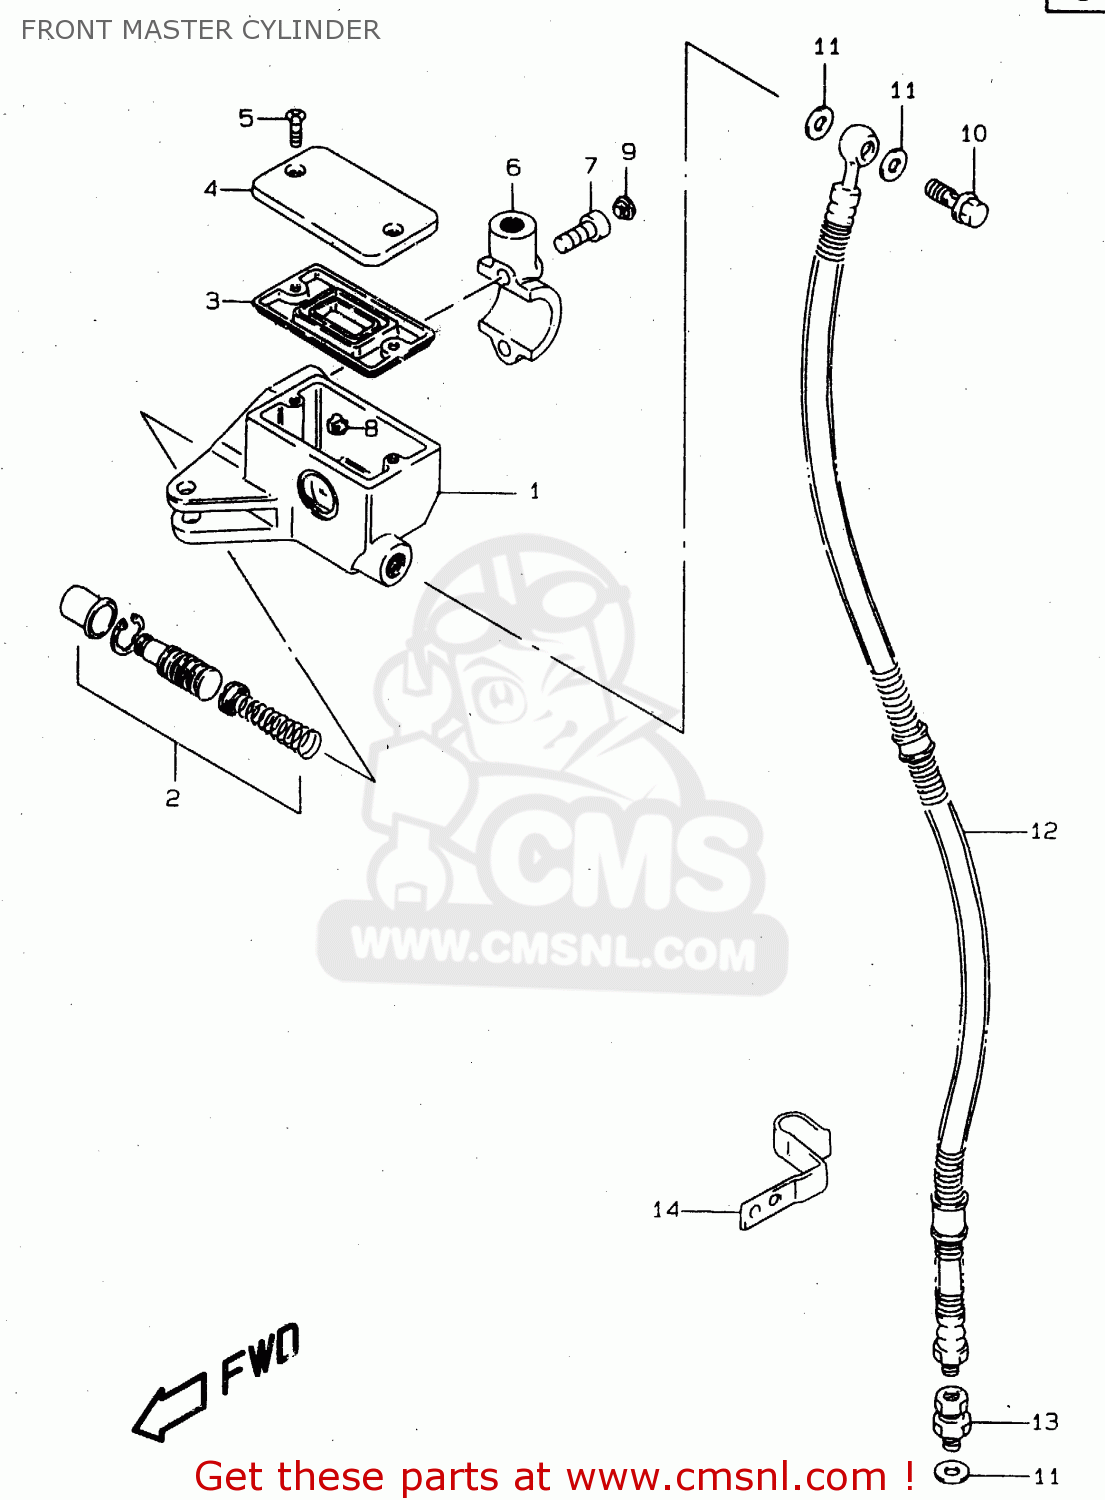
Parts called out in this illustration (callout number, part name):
1	CYLINDER ASSY,FR MASTER
2	PISTON/CUP SET
3	4
4	CAP
5	SCREW
6	HOLDER
7	BOLT
8	PROTECTOR
9	CAP(OD:10)
10	BOLT UNION
11	WASHER(10X15X1.5)
12	HOSE,FR BRAKE
13	ADAPTER,BRAKE HOSE
14	GUIDE,BRAKE HOSE
